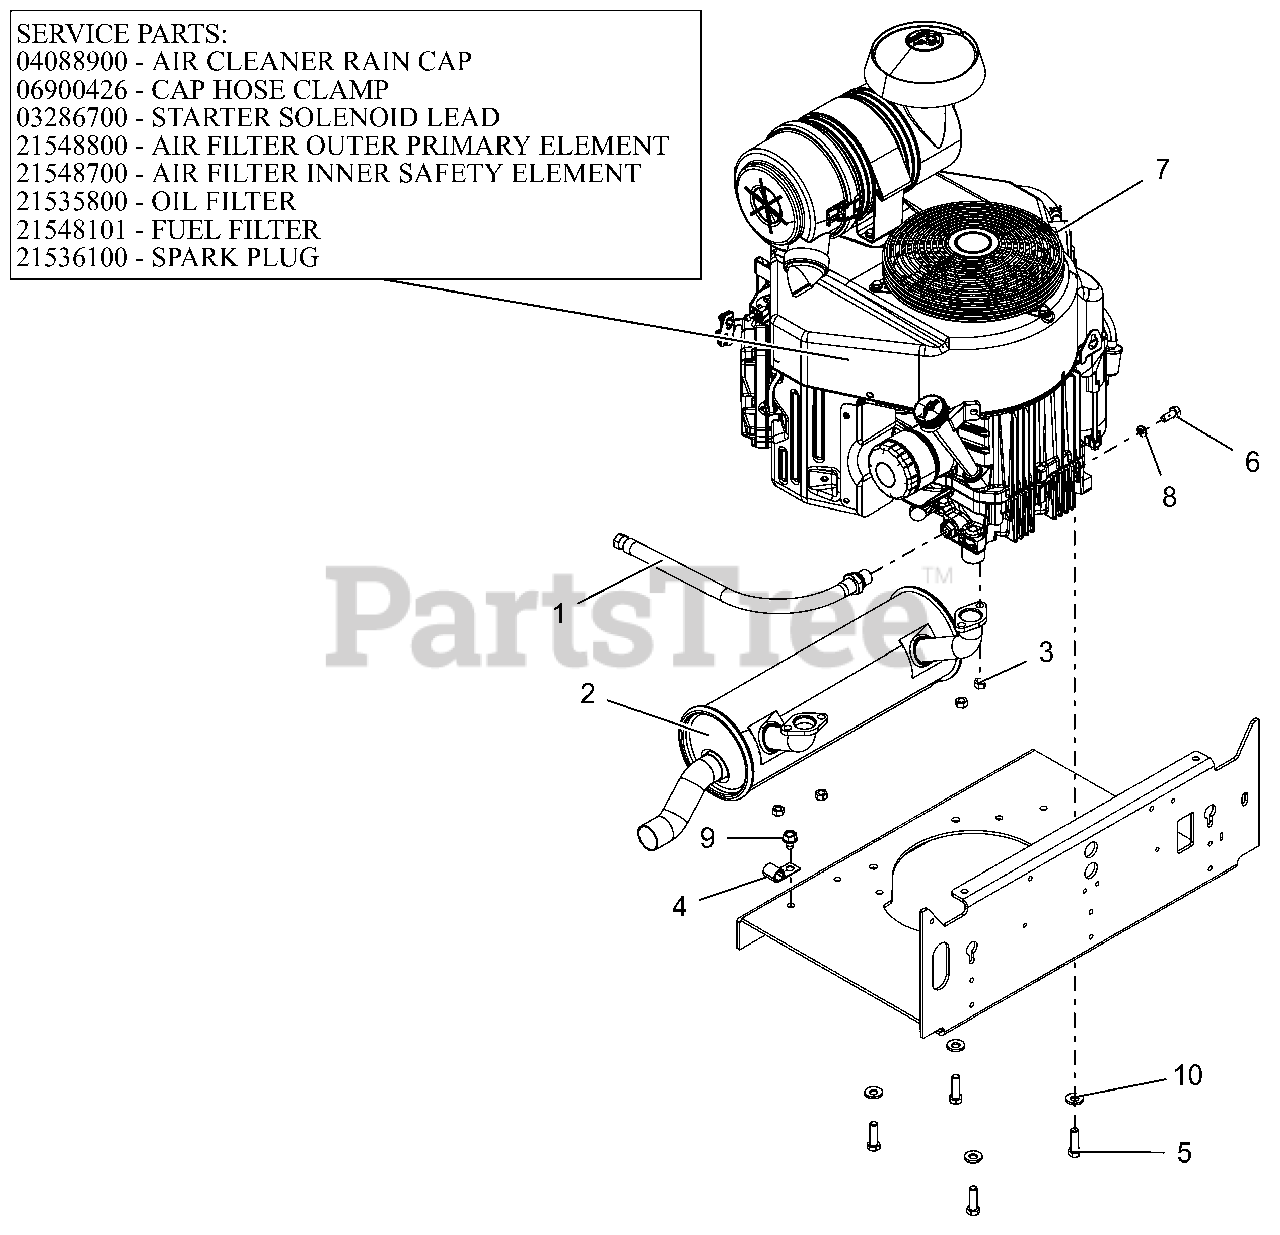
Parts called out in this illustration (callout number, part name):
1	HOSE, OIL DRAIN
2	MUFFLER, KAW FX691/730
3	NUT-LK-TOP M8-1.25 YWZC
5	BLT-HEX.38-16X1.25 G5YZ NYTORQ
6	@BLT-HEX M8-1.25X20 YWZC
7	ENGINE, KAWASAKI FX691
7	CAP, KAW 11065-7025
7	CLAMP, HOSE #36 SS 1.813-2.75
7	LEAD - STARTER SOLENOID
7	FILTER, OUTER
7	FILTER, INNER - KAW
7	FILTER,OIL - KAW
7	FUEL FILTER-KAWASAKI FR
7	PLUG, SPARK
8	@WSHR-LK .31X.078 REG YWZC
9	@SCR-TAP .38-16X.50 HWH TR YWZ
10	WASHER, 3/8" SPRING DISC
